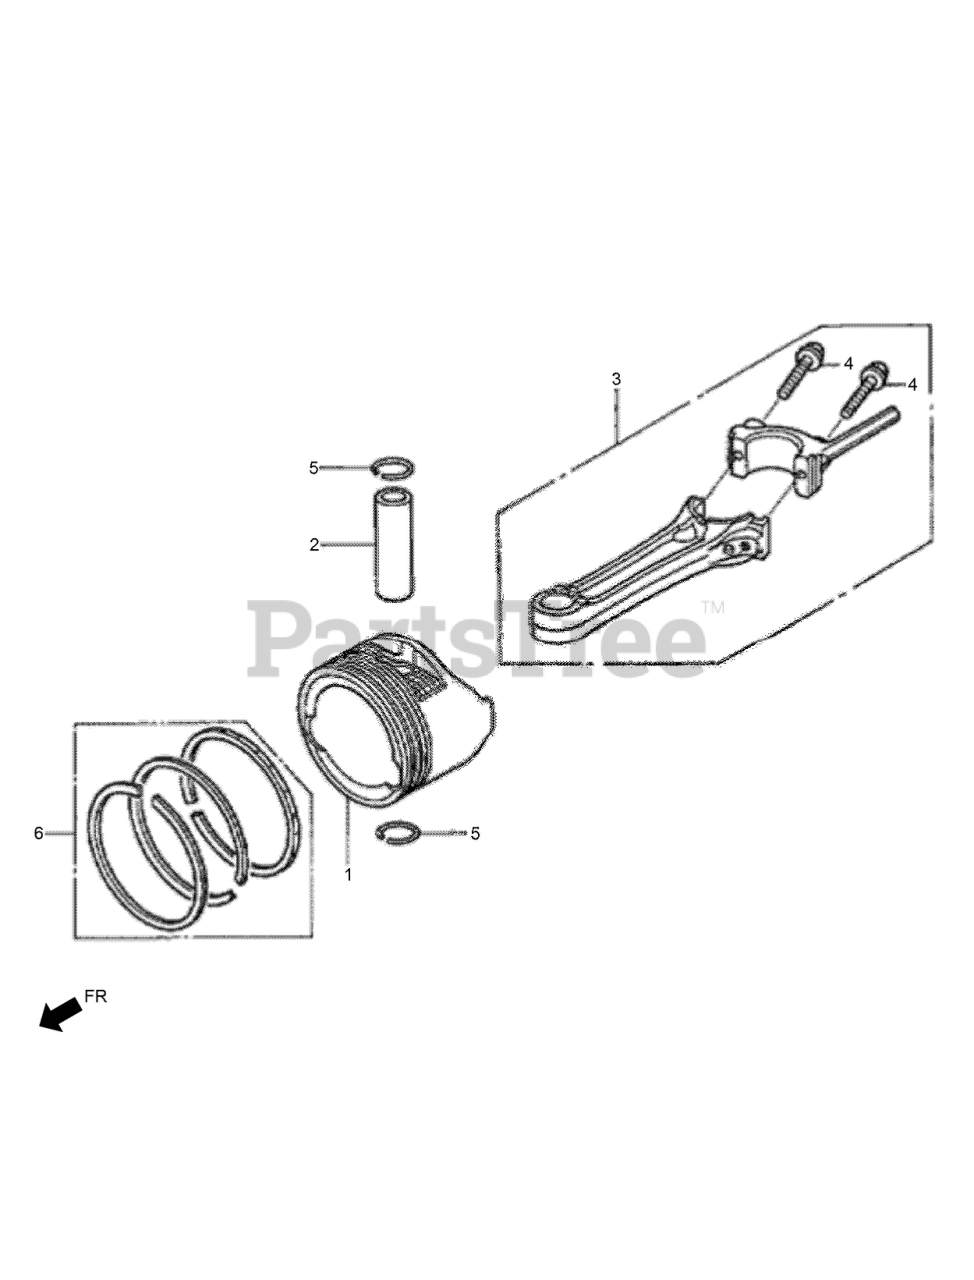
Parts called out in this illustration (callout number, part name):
1	PISTON (to S/N 3406723)
1	PISTON (from S/N 3406724)
2	PIN-PISTON (to S/N 3406723)
2	PIN-PISTON (from S/N 3406724)
3	ROD ASM-CONNECTING
4	BOLT-CONNECTING ROD
5	CLIP-PISTON PIN-13MM
6	RING SET-PISTON (STD)
